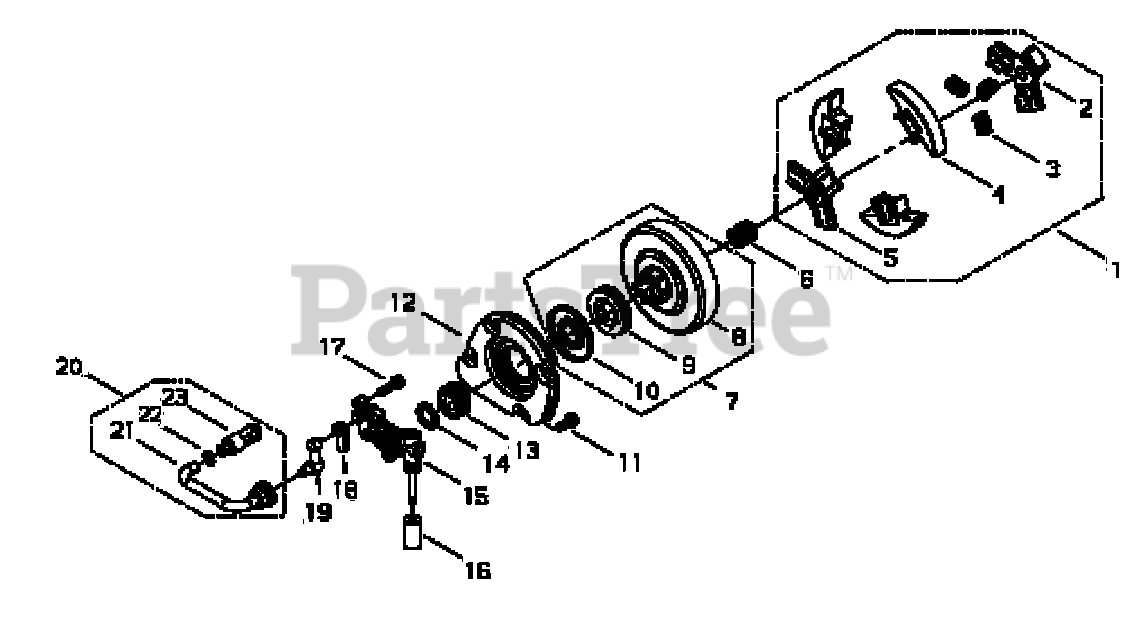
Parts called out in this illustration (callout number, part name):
1	CLUTCH ASSY
2	BOSS, CLUTCH B
3	SPRING, CLUTCH
4	SHOE, CLUTCH
5	BOSS, CLUTCH A
6	BEARING, NEEDLE 10
7	DRUM ASSY, CLUTCH
8	DRUM, CLUTCH
9	SPROCKET, 0.325 RIM
10	COVER
11	SCREW
12	PUMP COVER, FLOCKED
13	GEAR
14	PLATE, THRUST
15	OIL PUMP ASSY
16	FILTER
17	SCREW M4×16
18	GASKET, OIL PUMP
19	ELBOW
20	PIPE ASSY, OIL
21	PIPE, OIL
22	CLIP, OIL FILTER
23	FILTER, OIL
